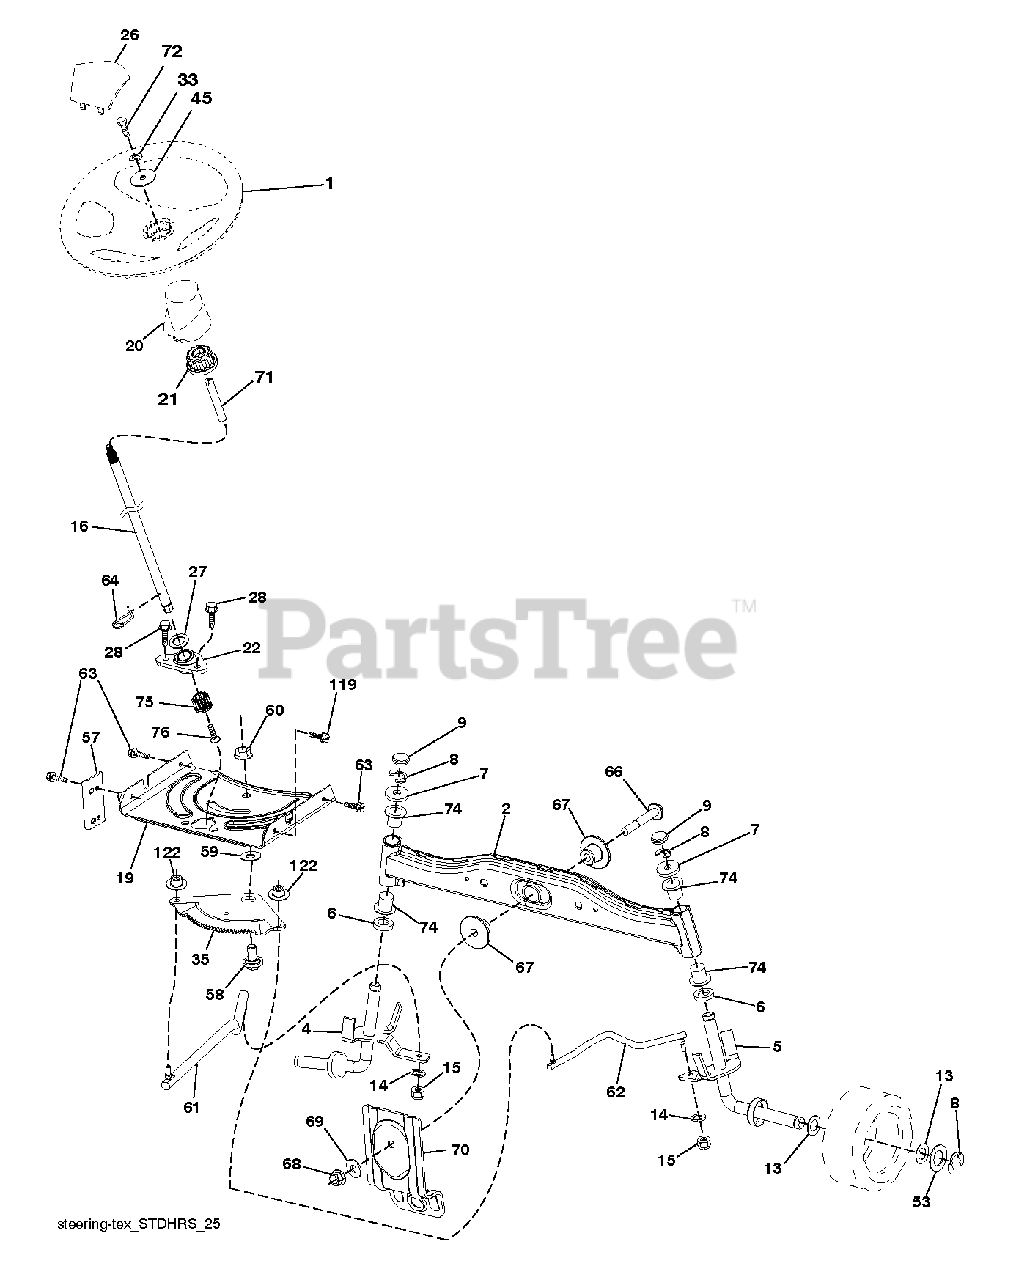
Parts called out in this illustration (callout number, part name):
1	WHEEL.STEERING.HUSQ.PREM.HRDRM
2	AXLE HALF ASM-WELDED
4	SPINDLE.STEERING.ASM.LH.13".TI
5	SPINDLE.STEERING.ASM.RH.13".TI
6	THRUST WASHER
9	CAP.SPINDLE.BLACK
14	SLW 3/8 STD
15	NUT CROWNLOCK 3/8-24
16	3 HIGH.SHAFT-ZINC.PLATED
19	PLATE.STEER.DDL.NLT/NG
20	STEERING.BOOT.HUSQ.LT
21	ADAPTER, WHEEL STNG..
22	BEARING.SHAFT.STEER.LOWER.625
26	INSERT.CAP.WHL.STRG.HUSQ.PREM
28	SCREW, 3/8-16X3/4
33	WASHER 5/16 LOCK
35	GEAR.SECTOR.PLATE.DDL.
45	WASHER.11/32
53	WASHER.HARDENED
57	BRACKET.UPSTOP.TEX
58	BOLT.SHOULDER.SECTOR.P
59	WASHER.THURST.SECTOR.S
60	NUT FLANGE LOCK 5/8-11
61	DRAGLINK.LH.BALLSTUD.D
62	DRAGLINK.RH.BALLSTUD.D
63	SCREW
64	RETAINER.CLIP.SPRING.S
66	BOLT HEX FGHD 7/16-14 X 3 SERR
67	BUSHING.PM.FRONT AXLE
68	NUT.LOCK.FLANGE.7/16
69	WASHER.1.5X.505X.118
70	BRACKET.SUSP.MWR.FRT.30"SRD
71	SHAFT.EXTEN.STRG.SPLINE
72	BOLT 5/16-18 X 4 W/PATCH
74	BRNG T
75	PINION.ZINC PLATED
76	SCREW HEAD SOCKET LRVB
119	SHOULDER BOLT 5/16-18TT
122	CAP.GEAR.SECTOR.TEX
